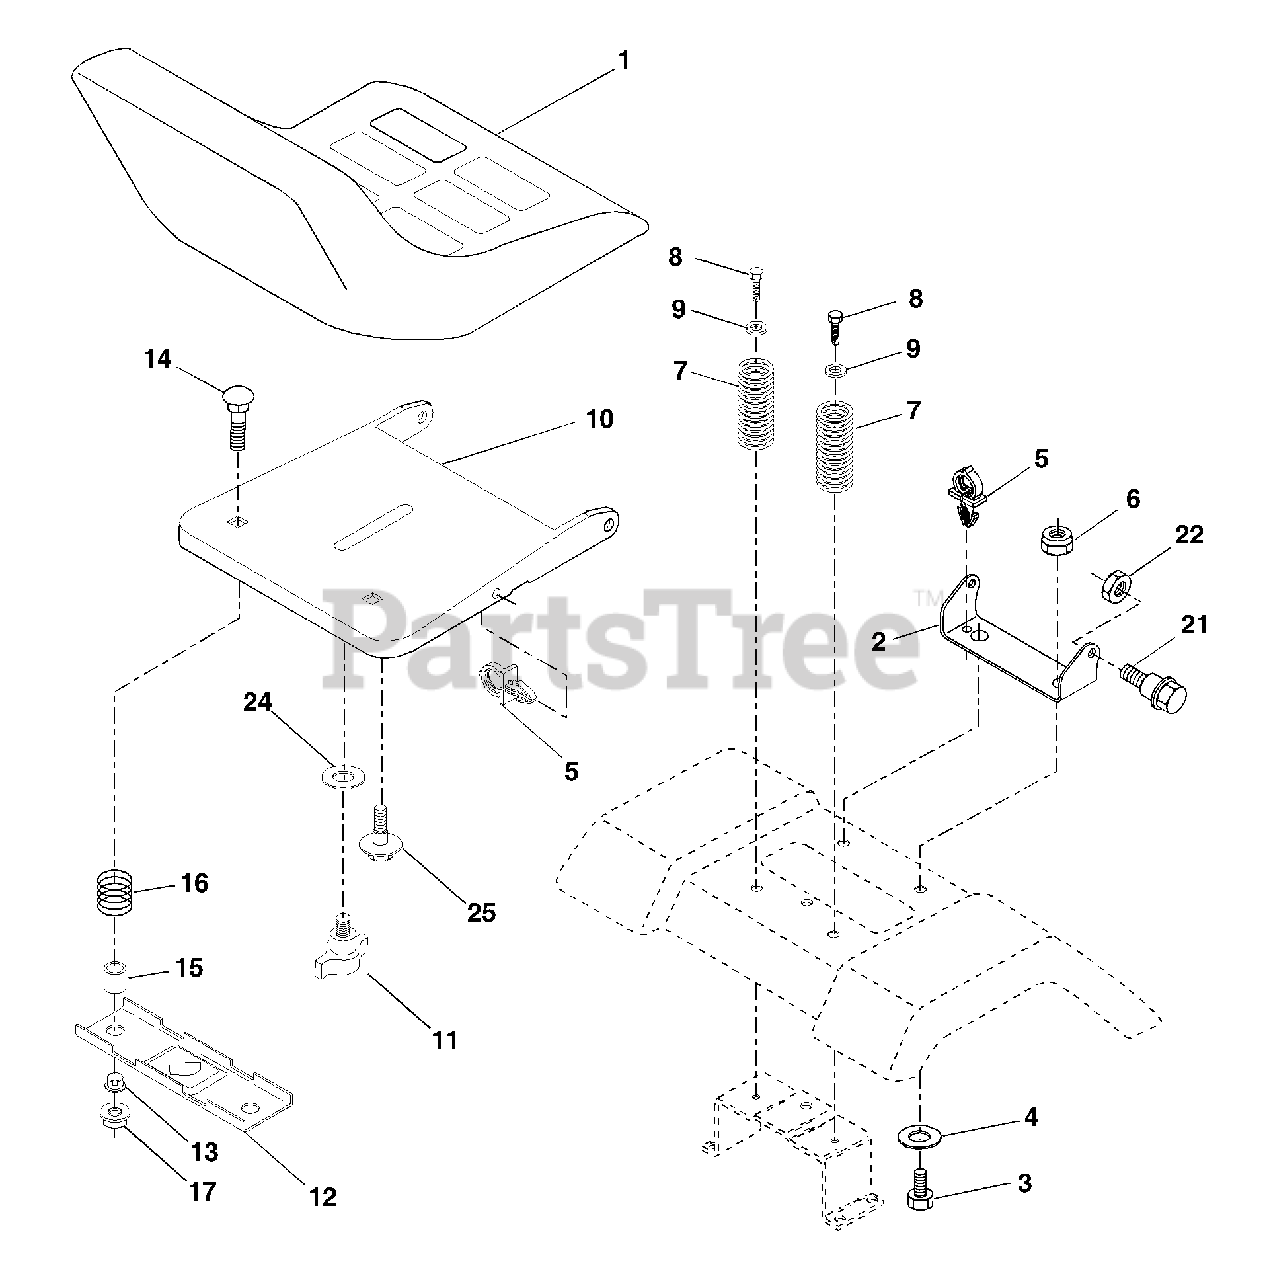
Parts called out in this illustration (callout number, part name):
1	Seat
2	Bracket Pivot Seat 8 720
3	Bolt Fin Hex 3/8-16 Unc x 1
4	Washer Flat 13/32 x 1 x 10 Ga.
5	Clip Push-In
6	Nut Hex w/Ins. 3/8-16 Unc
7	Spring Seat Cprsn 2 250 Blk Zi
8	Screw 3/8-16 x 1
9	Washer 13/32 x 1 x 14 Ga.
10	Pan Seat
11	Knob Seat Adj. Wingnut
12	Bracket Mounting Switch
13	Bushing Snap Blk Nyl 50 Id
14	Bolt Rdhd Sqnk 1/4-20x1-1/2
15	Spacer Split 28x 88
16	Spring Cprsn
17	Nut Lock 1/4 Lge Flg Gr 5 Zinc
21	Bolt Shoulder 5/16-18 Unc
22	Nut Hex Lock W/Ins 5/16-18
24	Washer 17/32 X 1-3/16 X 12 Ga.
25	Bolt Shoulder 5/16-18 X 62
